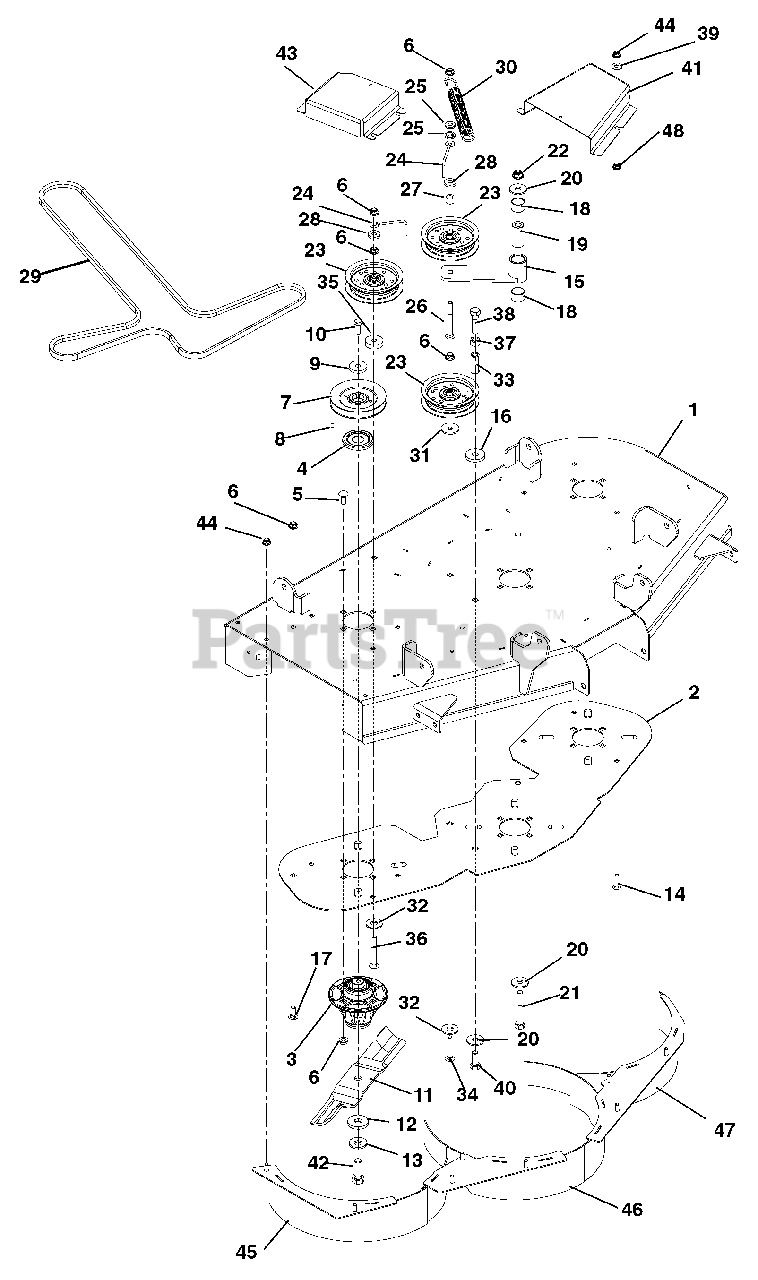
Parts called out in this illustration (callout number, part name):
1	WMT-42" DECK ZTXL ARIENS
2	DOUBLER PLATE, 42 XL
3	SPINDLE ASSEMBLY
4	DUST CAP
5	@BLT-RDHDSQNK .38-16X1.25 G5YZ
6	@NUT-LK-NYL-FLG .38-16 YWZC
7	SHEAVE, 4.75 DIA A-SECTION
8	KEY, SQ .25 X .38 X .25
9	WSHR,FLT STL.406X1.50X.245YWZC
10	BLT-HEX .38-16X1.0 GR8 YZ EP30
11	BLADE, MULCH 14.50"
12	WSHR-FLT .640X1.75X.250 YWZC
13	WSHR-BLVL .669X1.535X.138
14	@BLT-RHDSHSQNK.31-18X1.25 G5YZ
15	WELDMENT, IDLER ARM
16	WSHR-FL-STL .515X1.625X.250 YZ
17	@BLT-RDHDSQNK .38-16X1.00 G5YZ
18	BRG, 1.00 X 1.12 X .75
19	BSHG, SPCR .502X.997X2.03 PM
20	WSHR-FL-STL.511X1.441X.125 YWZ
21	@BLT-HEX .50-13X3.25 GR5 YWZC
22	@NUT-LK-NYL-FLG .50-13 YWZC
23	ASM, IDLER 4"
24	BELT FINGER
25	BSHG-FLG .406X.88X.270X.140
26	@BLT-RDHDSQNK .38-16X3.50 G5YZ
27	BSHG-SLV .391X.688X.52 PM
28	WSHR-FL-STL .406X1.00X.188 YWZ
29	V-BELT, HA-WRAPPED
30	EXTENSION SPRING
31	WSHR-FL-STL .390X1.5X.125 YWZC
32	@WSHR-FL-STL.563X1.38X.109YWZC
33	NUT, COUPLING 1/2-13X1.75 YWZC
34	@BLT-RDHDSQNK .38-16X2.25 G5YZ
35	SPACER, .39 X 1.50 X .380
36	@BLT-RDHDSQNK .38-16X3.00 G5YZ
37	@NUT-HEX .50-13 YWZC
38	@BLT-HEX .50-13X2.00 GR5 YWZC
39	@WSHR-FL-STL.38X.875X.083 YWZC
40	@BLT-HEX .50-13X1.25 GR5 YWZC
41	BELT COVER, LEFT GRAVELY 40
41	BELT COVER, LEFT
42	BLT-HEX .62-18X1.75 GR8 YWZC
43	BELT COVER, RIGHT GRAVELY
43	BELT COVER, RIGHT
44	@NUT-LK-NYL-FLG .31-18 YWZC
44	BELT COVER, RIGHT
45	WMT, 42 MULCH BAFFLE (RH)
46	WMT, 42 MULCH BAFFLE (CTR)
47	WMT, 42 MULCH BAFFLE (LH)
48	NUT- JAM .312-18 YWZC
